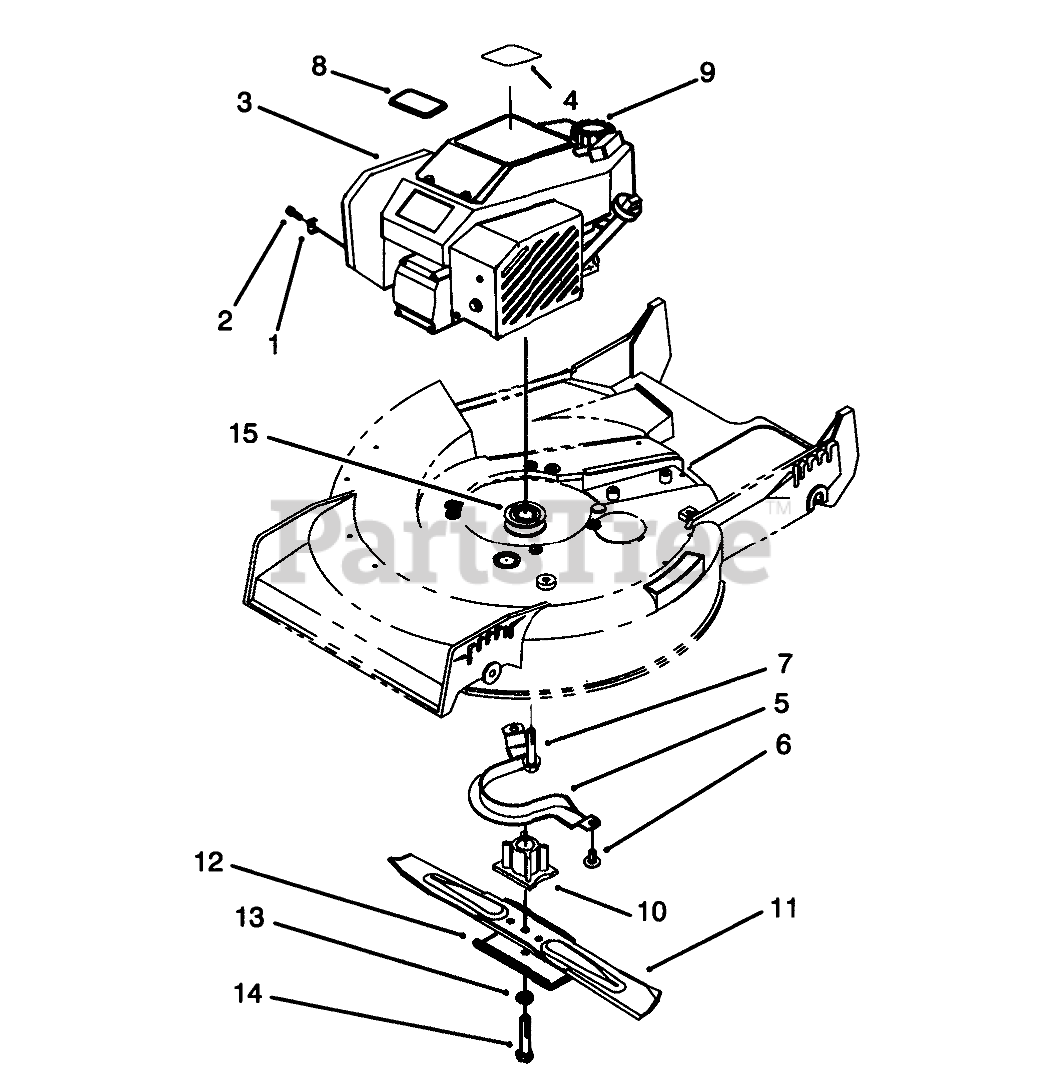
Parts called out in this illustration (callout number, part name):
1	CLAMP-CASING
2	Screw
3	ENG ASM-GTS 150 NC
4	DECAL - ENGINE
5	Guide-Belt
6	SCREW-HWHTF
7	SCREW-HWH
8	TORO LOGO PLATE
9	GAS CAP ASM
10	BLADE RETAINER
11	Blade
12	Stiffener
13	WASHER-LOCK
14	SCREW-BLADE
15	PULLEY-DRIVE, ZONE START
